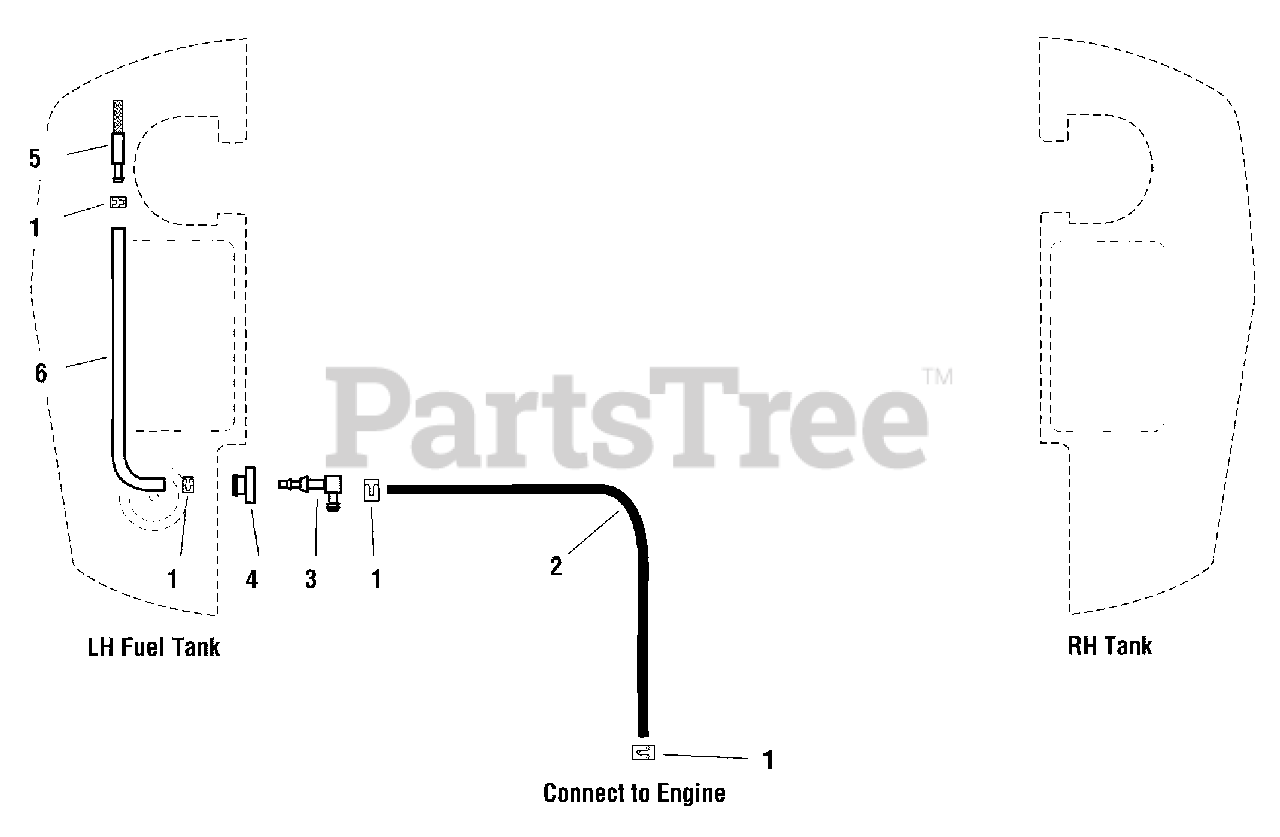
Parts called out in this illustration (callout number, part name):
1	CLAMP, HOSE, EXTERNAL, 1/2 - RED
2	HOSE, 1/4" FUEL, 22.00"
3	FITTING, ELBOW
4	BUSHING, FUEL TANK
5	FITTING, SCREEN
6	HOSE, 1/4" FUEL, 28.00"
